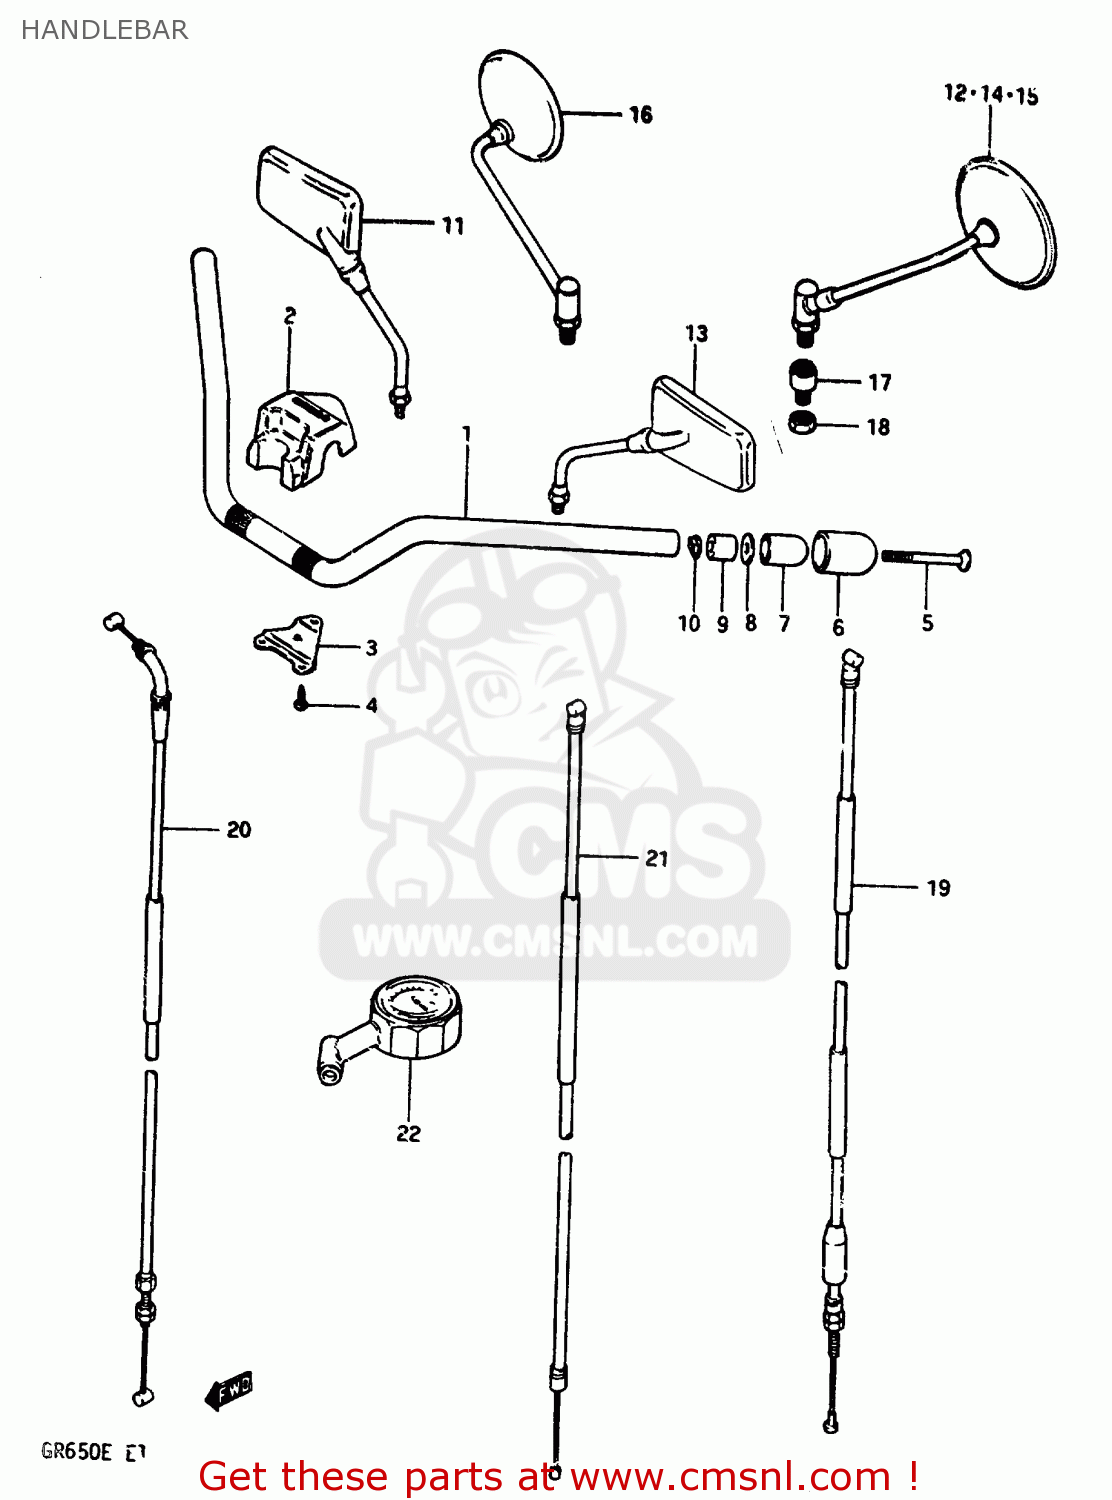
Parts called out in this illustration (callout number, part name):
1	HANDLEBAR
2	COVER,STEERING HEAD
3	BRACKET,STEERING HEAD
4	SCREW
5	SCREW 6X65
6	CAP,BALANCER
7	BALANCER,HANDLE
8	SPACER,BALANCER
9	EXPANDER,BALANCER
10	NUT
11	MIRROR, REAR VIEW RH
12	MIRROR ASSY,RH
13	MIRROR, REAR VIEW LH
14	MIRROR, REAR VIEW LH
15	MIRROR ASSY,RH
16	MIRROR ASSY, REAR VIEW
17	CUSHION,REAR VIEW MIRROR
18	NUT
19	CABLE ASSY,CLUTCH
20	CABLE ASSY,THROTTLE
21	CABLE COMP,STARTER
22	GAUGE ASSY,AIR PRESSURE
